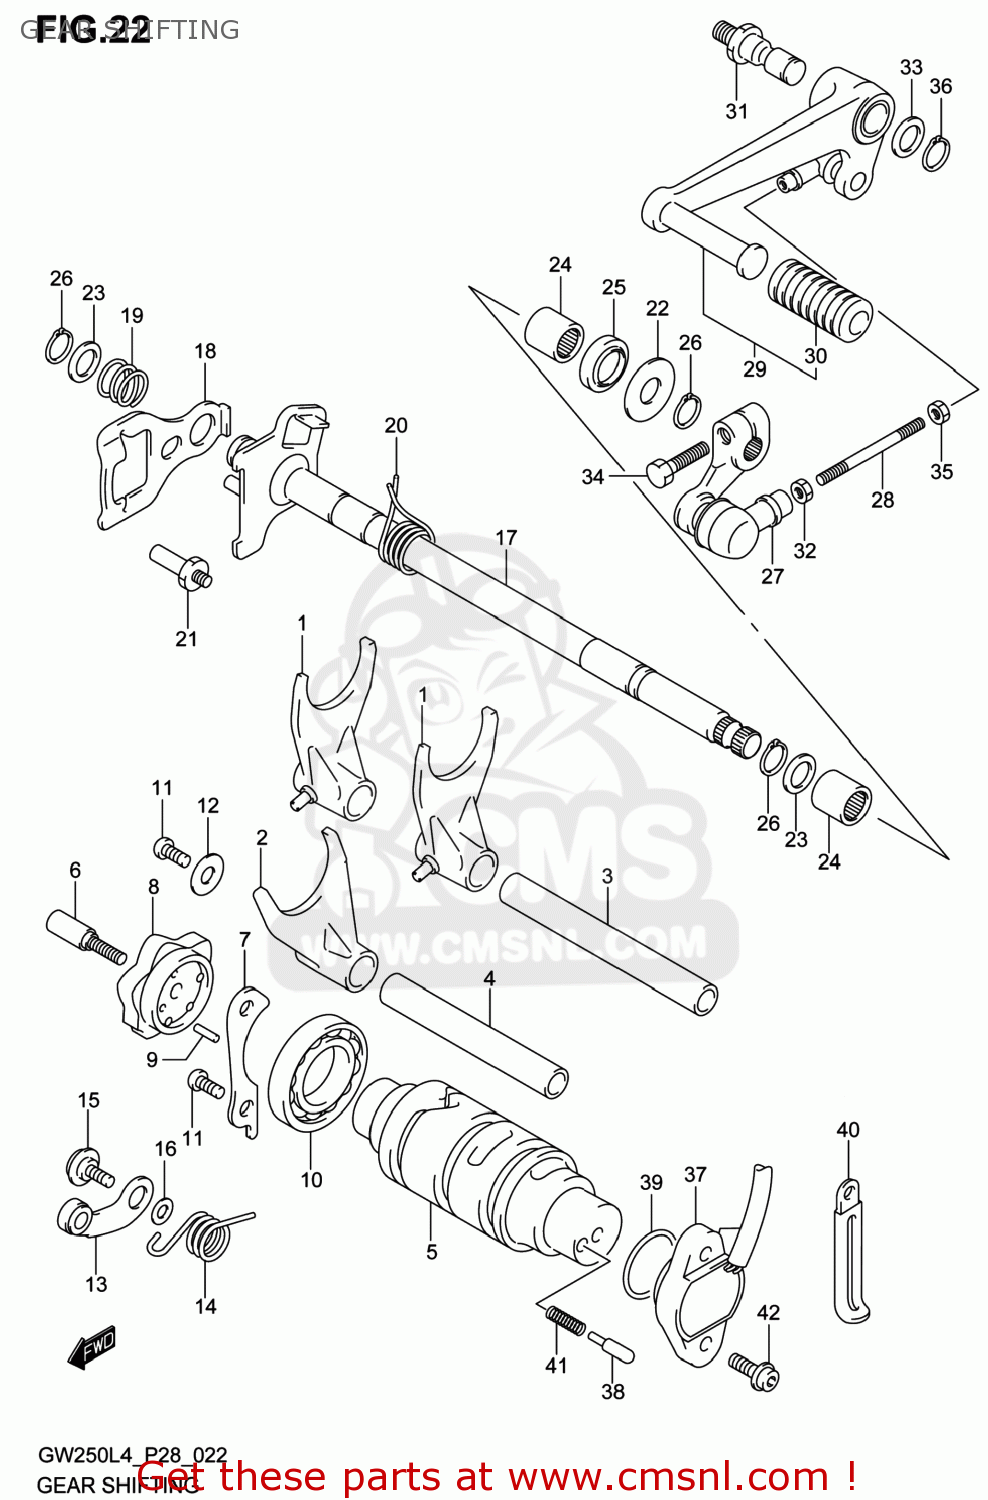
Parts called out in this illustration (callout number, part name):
1	FORK,GEAR SHIFT NO.1
2	FORK,GEAR SHIFT NO.2
3	SHAFT,GEAR SHIFT FORK NO.1
4	SHAFT,GEAR SHIFT FORK NO.2
5	CAM,GEAR SHIFT
6	STOPPER,SHIFT CAM DRIVE PLATE
7	RETAINER,SHIFT CAM BRG NO.1
8	PLATE,GEAR SHIFT CAM
9	PIN(3X9.8)
10	BEARING(25X47X8)
11	SCREW
12	WASHER
13	STOPPER,GEAR SHIFT CAM
14	SPRING,GEAR SHIFT CAM STOPPER
15	BOLT(6X14.5)
16	WASHER
17	SHAFT,GEAR SHIFT
18	PLATE,GEAR SHIFT CAM DRIVE
19	SPRING,GEAR SHIFT PLATE RETURN
20	SPRING,SHIFT SHAFT RETURN
21	STOPPER,GEAR SHIFT ARM
22	WASHER(14X29X0.8)
23	WASHER(14X22X1)
24	BEARING(14X20X12)
25	SEAL,OIL(14X22X7.3)
26	CIRCLIP
27	ARM,GEAR SHIFT LINK
28	ROD,GEAR SHIFT LINK
29	LEVER ASSY,GEAR SHIFT
30	RUBBER,GEAR SHIFT PEDAL
31	SHAFT,GEAR SHIFT LEVER
32	NUT
33	WASHER(12.5X20X1)
34	BOLT
35	NUT
36	CIRCLIP
37	BASE ASSY,GEAR SHIFT TERMINAL
38	CONTACT
39	O RING(D:2.4,ID:26.2)
40	CLAMP(L:45)
41	SPRING
42	BOLT
